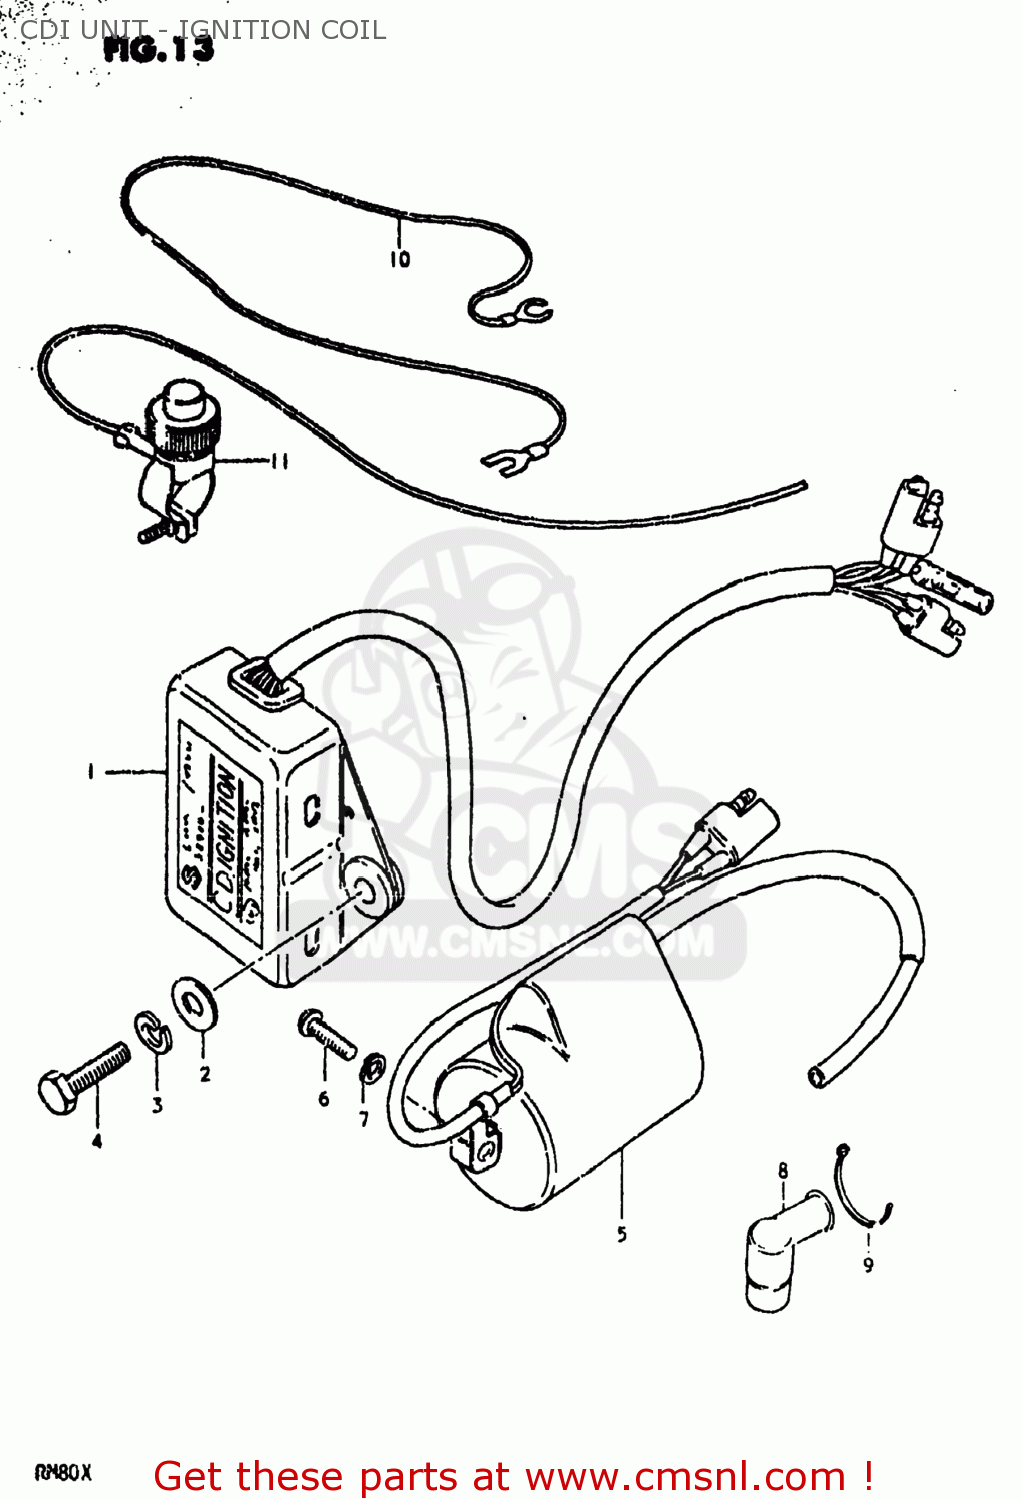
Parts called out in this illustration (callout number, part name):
1	CDI UNIT
2	WASHER(6.5X16X1.2)
3	LOCK WASHER
4	BOLT
5	COIL ASSEMBLY,IGNITION
6	SCREW 5X20
7	LOCK WASHER
8	CAP,SPARK PLUG
9	CLAMP
10	WIRE,ENGINE STOP EARTH
11	SWITCH ASSEMBLY
